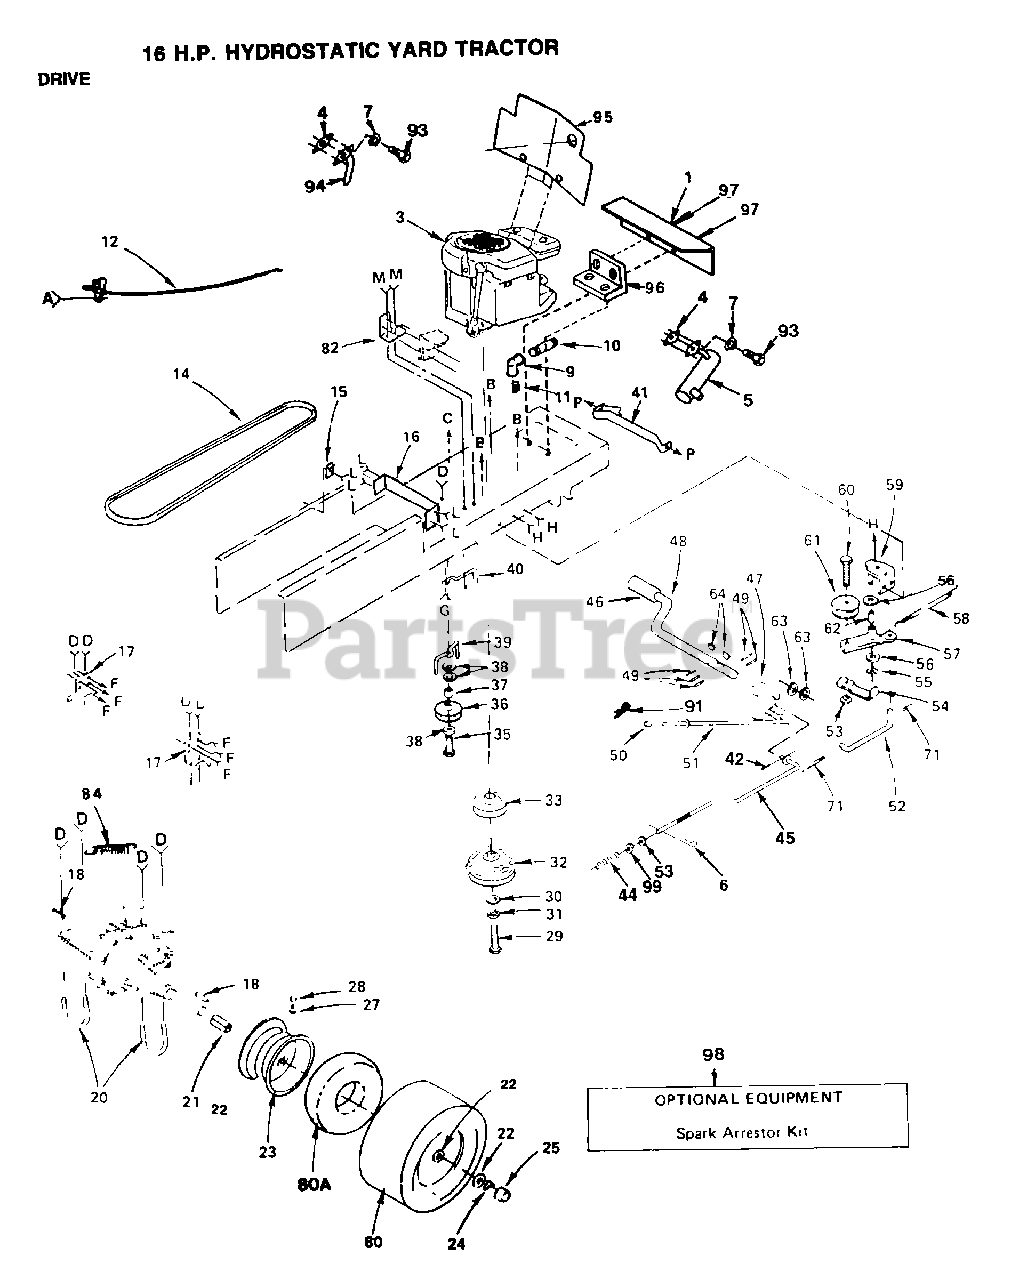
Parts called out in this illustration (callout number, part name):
1	BAFFLE - VERTICAL
2	SNAP BUSHING T
3	ENGINE 16 H.P. MODEL #402707 TYPE #1211 - 01
6	RETAINER M
7	LOCKWASHER
9	ELBOW
10	PIPE NIPPLE LT
11	PLUG OIL DRAIN
12	CONTROL THROTTLE
15	CLIP T
16	PLATE TRANS SUPT
19	NUT
20	U BOLT
21	SPACER SPLIT
22	WASHER
24	E-RING LT
25	HUB CAP
27	VALVE STEM LT
28	VALVE CAP
30	WASHER LT
31	LOCKWASHER
35	BOLT
37	SPACER T
38	WASHER
39	"KEEPER,BLT ENG LT"
40	KEEPER BELT ENGLH
42	COTTER PIN
44	SPRING ROD LT
45	ROD BRAKE
46	PEDAL COVER T
47	ARM BRAKE LT
48	FOOT SHAFT PEDAL
50	PLUNGER CAP T
52	"LINK, CLUTCH T"
55	KLIP RING
56	WASHER LT
57	"ASS T, BELLCRAN"
58	"SPRING, RETURN LT"
62	"LY, BEARING"
63	WASHER
64	KEY WOODRUFF #9
65	SCREW
66	SCREW LT
67	LOCKWASHER
69	BOLT
70	BOLT
71	COTTER PIN
79	LOCKWASHER
80A	TUBE.18X9.5-8
82	BRACKET LT
83	SCREW
88	WASHER
89	BOLT
91	SPRING.RETAINER
92	SCREW LT
94	EXHAUST TUBE T
96	BRACKET HEAT SHIELD
97	SCREW LT
99	NUT
